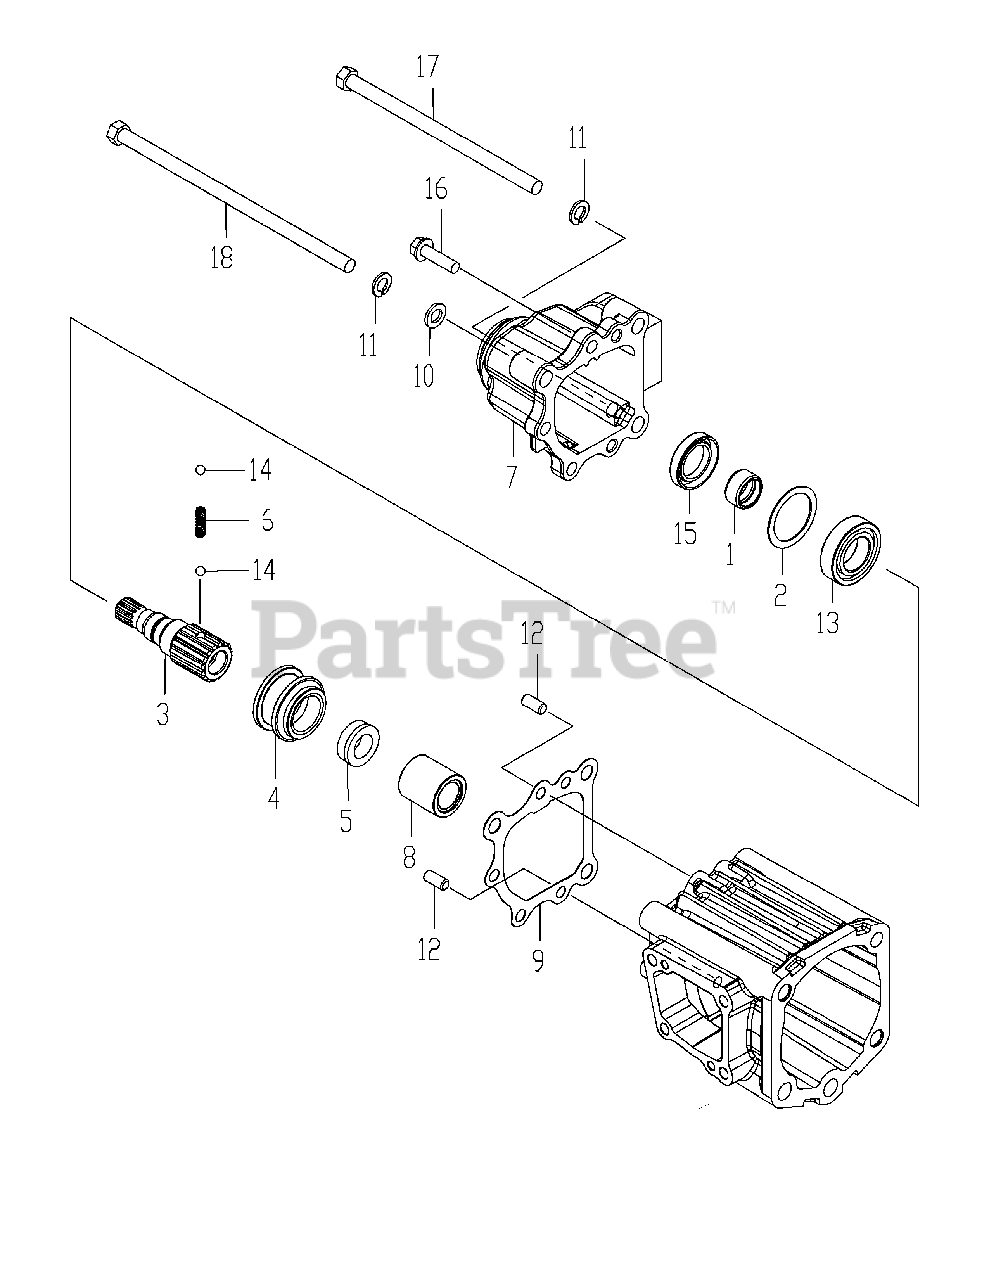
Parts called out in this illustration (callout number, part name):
1	SLEEVE, SI20X25X13
2	WASHER, 36X46X1
3	SHAFT, FRONT DRIVE
4	COLLAR, FRONT SHIFT
5	COLLAR, FRONT SPLINE
8	SPACER, 20X33X285
9	PACKING, FRONT COVER
13	BEARING, 6005 NTN
15	SEAL, TC254008
17	BOLT, 10 X 180
18	BOLT, 10 X 220
